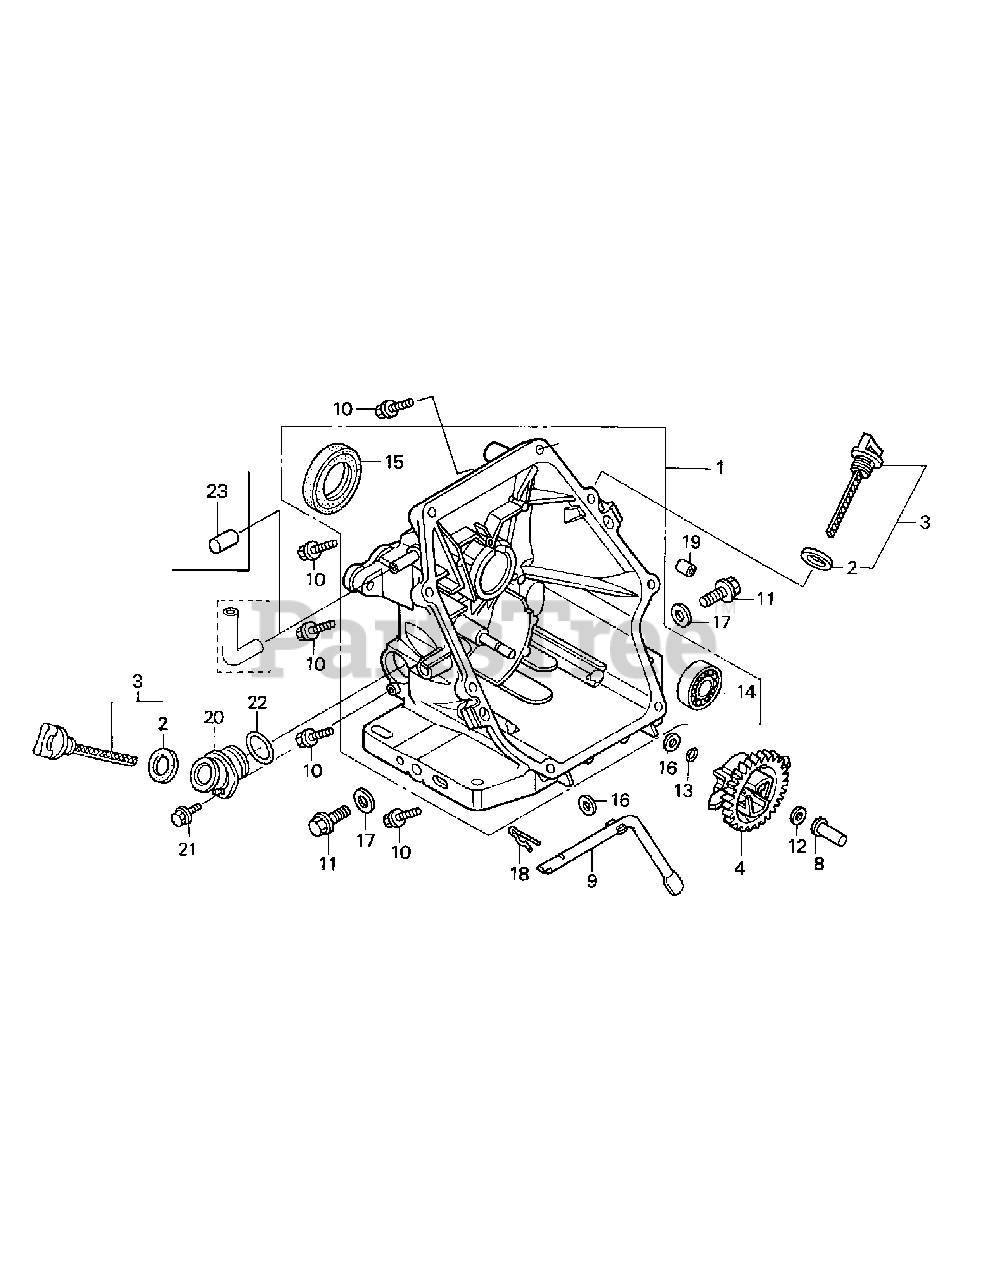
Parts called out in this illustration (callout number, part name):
1	Crankcase Cover Assembly
2	Oil Filler Gas Cap
3	Oil Level Gauge Assembly
4	Governor Assembly
8	Governoe Slider
9	Governor Arm Shaft
10	Flange Bolt, 6 x 25
11	Drain Plug Bolt
12	Thrust Washer, 6mm
13	Governor Holder Clip
15	Oil Seal, 28 x 41.25 x 6
16	Plain Washer, 6mm
17	Drain Plug Washer, 12mm
18	Lock Pin, 8mm
19	Dowel Pin, 8 x 20
